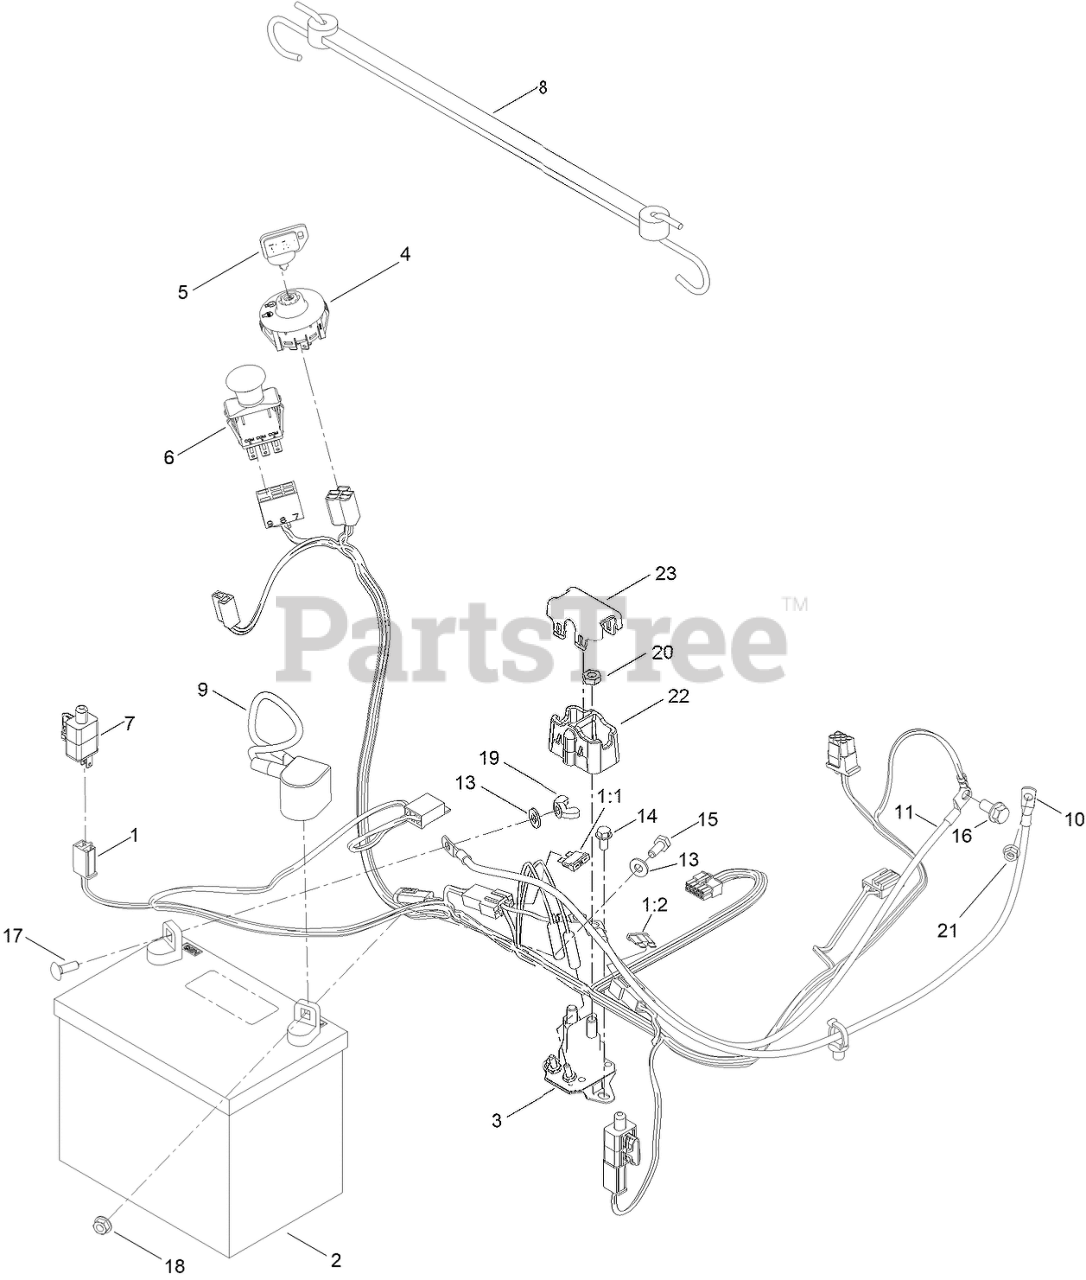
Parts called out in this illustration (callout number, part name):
1	HARNESS-WIRE
1:1	FUSE-BLADE, 15 AMP
1:2	FUSE-BLADE, 25 AMP
2	BATTERY
3	SOLENOID
4	SWITCH-IGNITION
5	KEY-IGNITION
6	SWITCH-PTO
7	SWITCH
8	STRAP-RUBBER
9	CABLE-BATTERY, POS
10	CABLE-BATTERY, RED (8 GAUGE)
11	CABLE-BATTERY, BLACK
13	WASHER-FLAT
14	SCREW-HWH
15	SCREW-HH
16	SCREW-HHF
17	BOLT-CARR
18	NUT-HF
19	NUT-WING
20	NUT-JAM
21	NUT-HF
22	COVER-SOLENOID
23	CAP-SOLENOID
